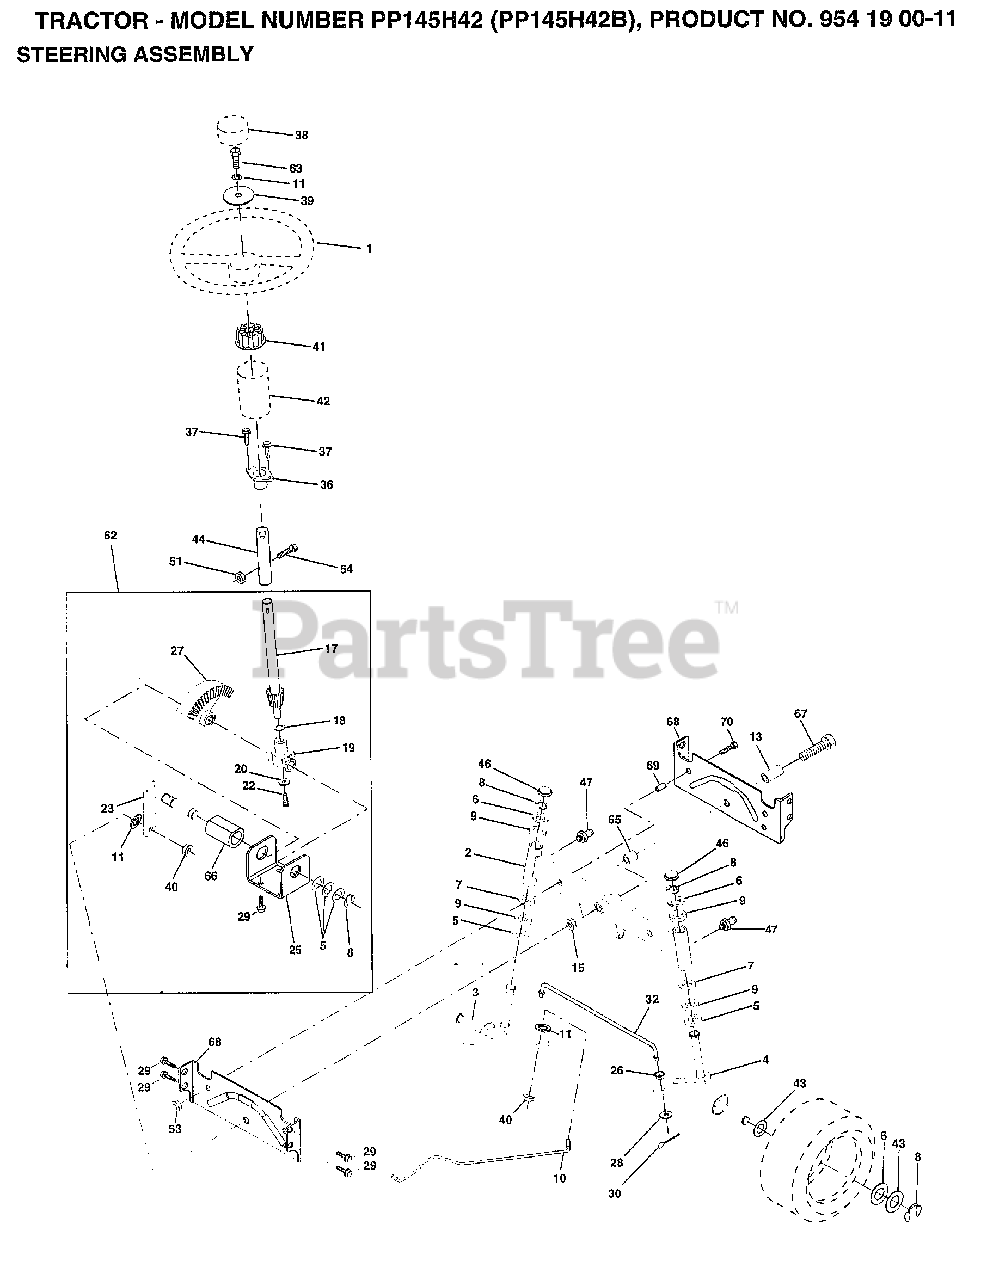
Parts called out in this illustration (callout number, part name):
2	AXLE ASM
3	SPINDLE.ASM.LH
4	"SPINDLE ASM,RH"
5	WASHER .T
6	WASHER
7	WASHER
8	RING
9	COL. SRTG. BEAR.
10	DRAGLINK-STAMPED
11	LOCKWASHER
13	BEARING AXLE
15	"NUT-LOC,FLANGE LT"
17	SHAFT ASM STEERIN
18	THRUST WASHER
19	SUPPORT SHAFT
20	WASHER SHIM 1/4 X 5/8 X 062
22	SCREW HEX SOC1/4-
25	BRKT-STEERING
26	BUSHING.DRAGLINK
27	GEAR SECTOR
28	WASHER
29	SCREW
30	COTTER PIN
32	TIE ROD
36	BUSHING.STEERING
37	"SCREW-TT,10-32 FL"
38	"INSERT,STR WHEEL"
39	WASHER T
40	GRIPCO NUT
41	ADAPTER LT
42	BOOT.STEER.PL
43	WASHER
44	EXT SHAFT STEERIN
46	CAP
47	ZERK M
51	NUT
54	BOLT
62	KIT STEERING ASM
63	BOLT
65	SPACER AXLE
66	"BEARING-ARM,PITMA"
67	BOLT
68	BRACE AXLE
69	"SPACER BRCAE,AXLE"
70	BOLT.HEX.3/8-16X2
